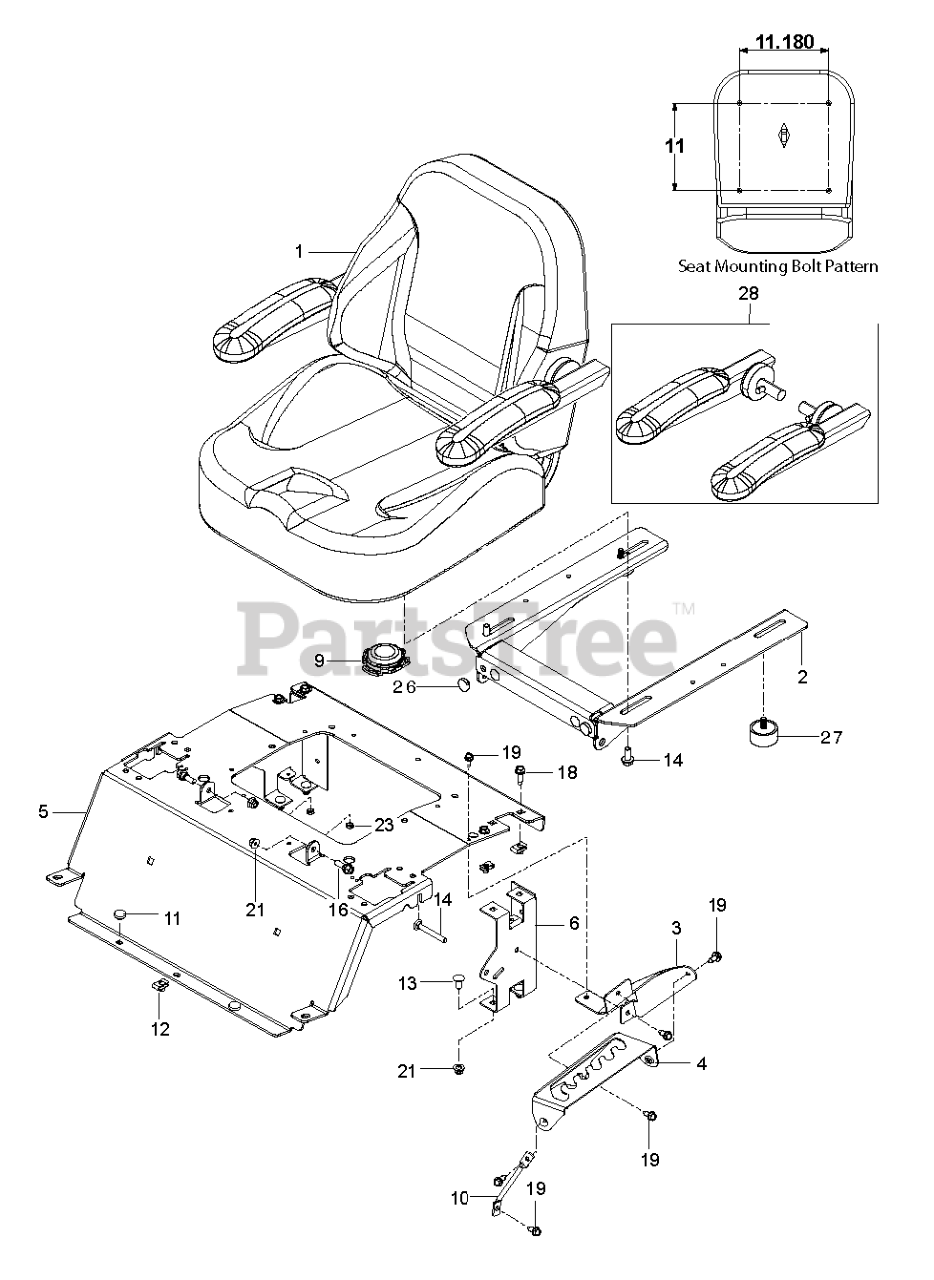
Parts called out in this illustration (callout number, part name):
3	PLATE.SUPPORT.DECK.LIFT.X431
4	PLATE.DECK.LIFT.X431
5	SUPPORT.SEAT.RZ.HUSQ.ORANGE
6	SUPPORT REAR SEAT BLACK
9	SWITCH.SEAT.DELTA.OPC.
10	SUPPORT.LEG.DECK.LIFT
11	WASHER
12	U-CLIP 5/16-18 NUT RETAINER
13	BOLT 5/16C X 3/4" CARRIAGE
16	BOLT, SHOULDER
18	SCREW.THDROL.5/16-18X3/4.TTY
19	BOLT.5/16HEX.WHS.HD
21	5/16-18 NYLOC FLANGE NUT
23	NUT
26	GROMMET, BUMPER
27	BUMPER 5/16-18 CLEAR ZINC
28	SEAT KING 18" WOOD BTM, ARM
